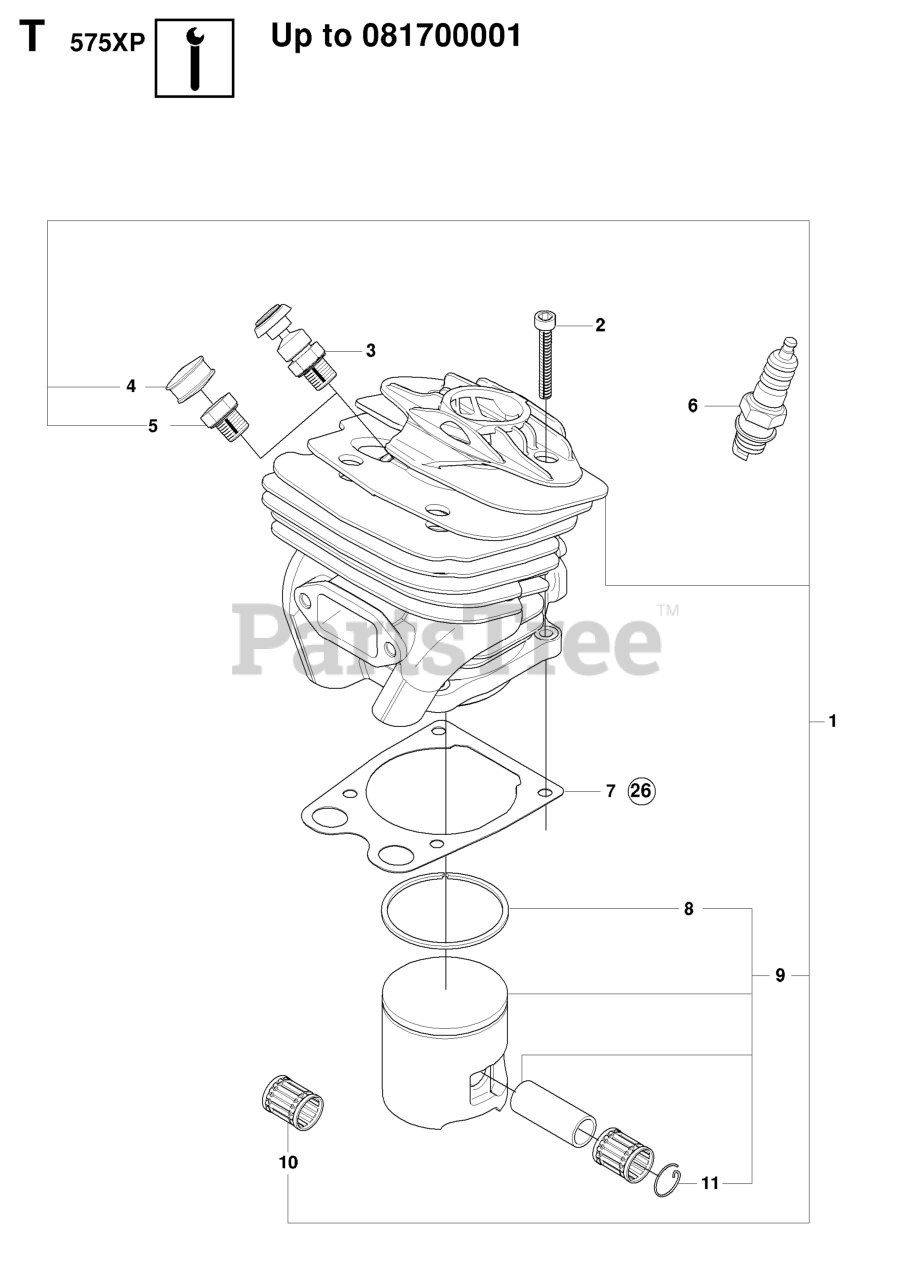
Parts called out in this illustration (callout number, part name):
1	%CYLINDER
2	SCREW MC6S 5X25
3	VALVE
5	CYLINDER PLUG
6	SPARK PLUG M14X1.25 NGK BPMR7A
8	PISTON RING
9	PISTON 49 MM
10	SUPPORT BUSHING
11	WRIST PIN CLIP
26	GASKET SET
